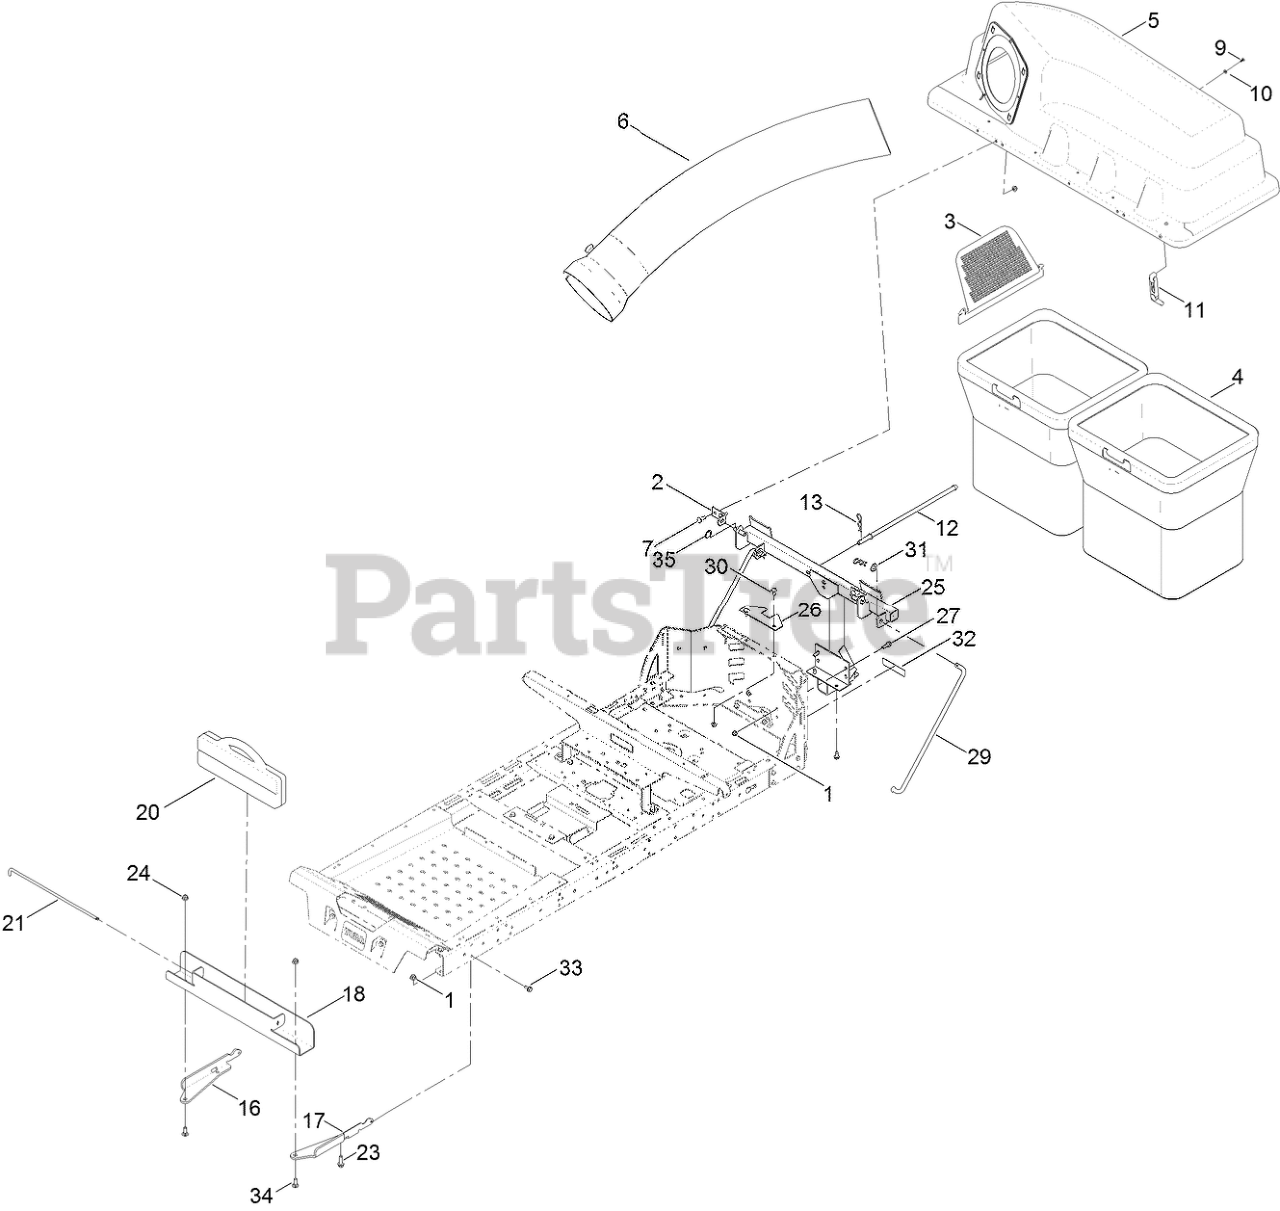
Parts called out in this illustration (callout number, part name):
1	NUT-HF, NI
2	BRACKET-PIVOT, HOPPER
3	SCREEN-BAGGER
4	BAG ASM
5	BAGGER TOP ASM
6	TUBE-BAGGER
7	BOLT-CARR
9	SCREW-PLASTITE
10	WASHER-FLAT
11	LATCH-RUBBER
12	ROD-HOOD, DOWN (HOLD)
13	PIN-HAIR
16	BRACKET-WEIGHT, RH
17	BRACKET-WEIGHT, LH
18	CHANNEL-WEIGHT, BAGGER
20	WEIGHT-35 POUND
21	PIN-WEIGHT
23	SCREW-HHF
24	NUT-HF, NI
25	FRAME-PIVOT
26	BRACKET-STABILIZER
27	SCREW-HHF
29	ROD-SUPPORT
30	BOLT-CARR
31	WASHER-FLAT
33	SCREW-HWHTF
34	BOLT-CARR
35	PIN-COTTER, CIRCULAR
